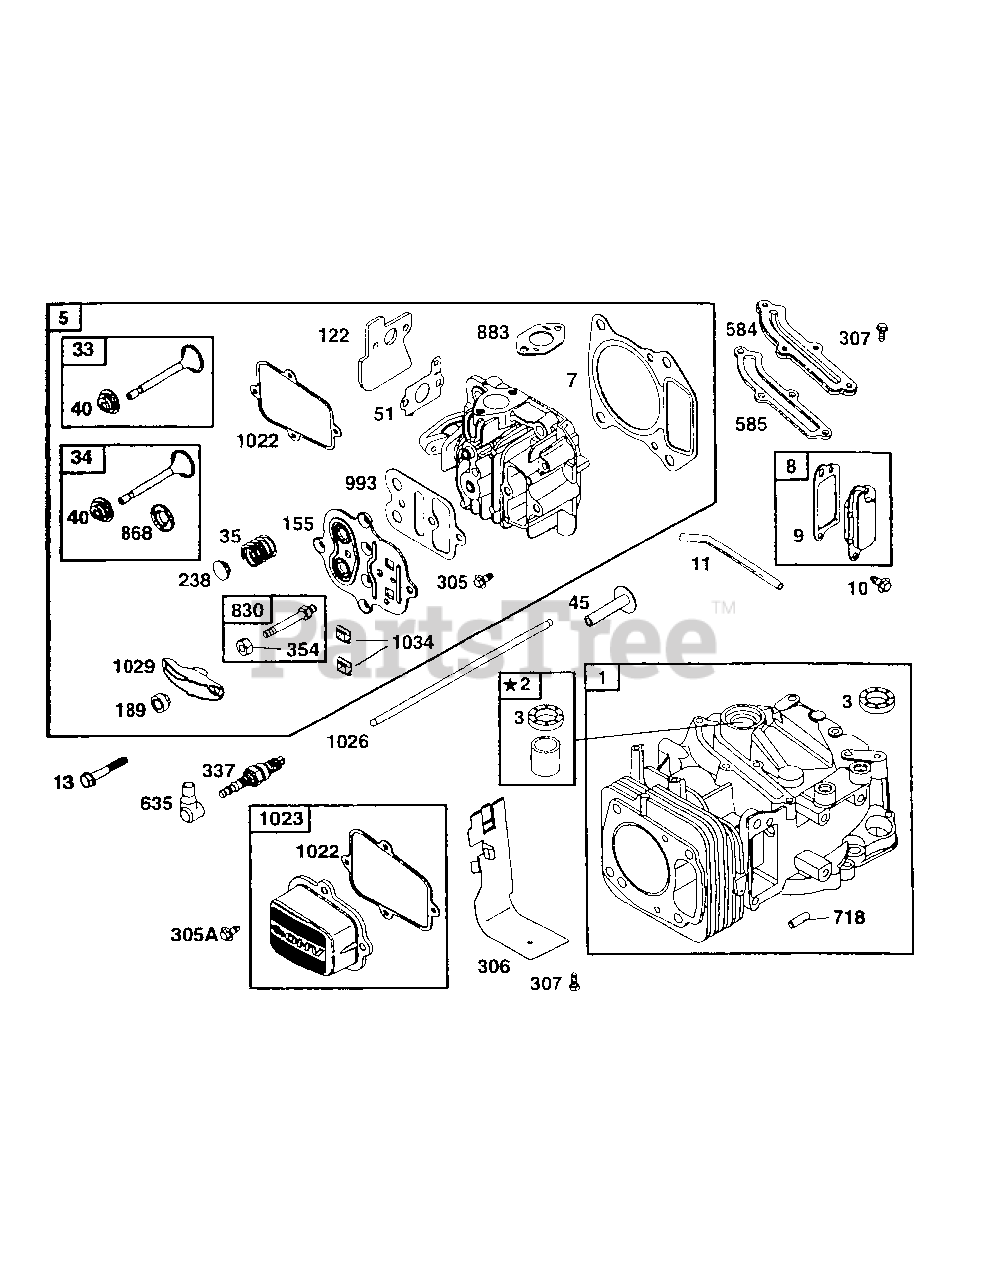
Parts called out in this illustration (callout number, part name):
1	Cylinder Assembly
2	Bushing
3	Seal-Oil
5	Cylinder Head
7	Cylinder Head Gasket
8	Breather Assembly
9	Breather Gasket
10	Screw-Hex
11	Breather Tube
13	Screw-Hex
33	Exhaust Valve
34	Intake Valve
35	Valve Spring
40	Valve Retainer
45	Valve Tappet
51	Intake Gasket
122	Carburetor Spacer
155	Cylinder Head Plate
189	Rocker Arm Ball
238	Valve Cap
305	Screw-Hex
305A	Screw-Hex
306	Cylinder Shield
307	Screw-Hex
337	Spark Plug
354	Lock Nut
584	Breather Passage Cover
585	Breather Passage Gasket
635	Spark Plug Boot
718	Locating Pin
830	Rocker Arm Stud
868	Valve Seal
883	Exhaust Gasket
993	Plate Gasket
1022	Rocker Cover Gasket
1023	Rocker Cover
1026	Push Rod
1029	Rocker Arm
1034	Push Rod Guide
